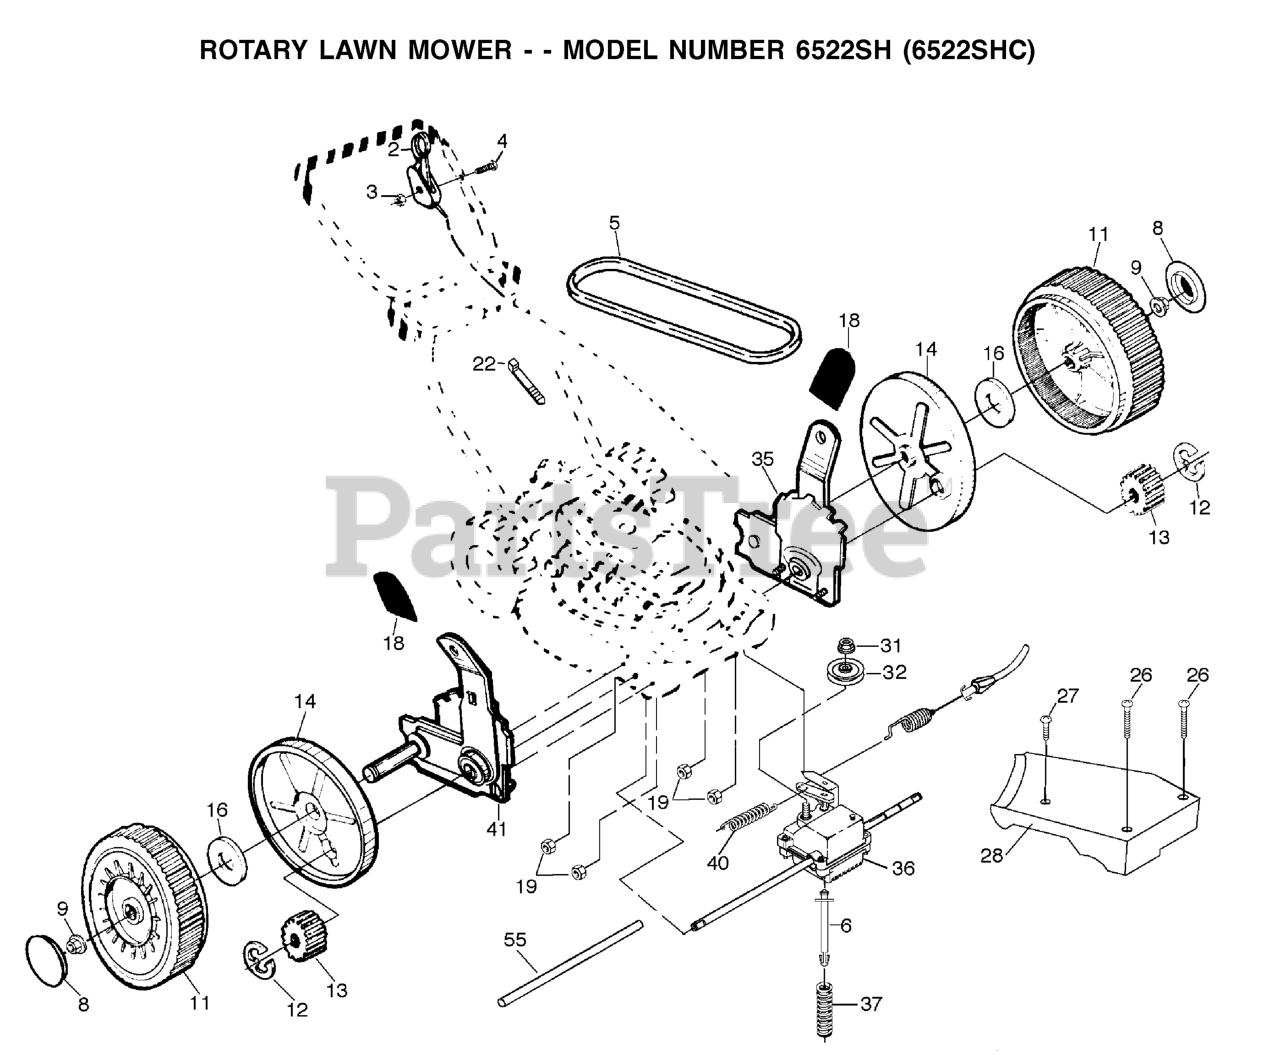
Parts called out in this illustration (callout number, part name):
2	CONTROL
3	LOCK NUT
4	SCREW.PAN.HEAD
5	BELT THERM .32
6	SPRING RETAINER
8	CAP.HUB.BLACK.WALK
9	NUT
11	WHEEL.8X2.PR.LP.RADII.GY
12	E-RING 7/16 RE
13	PINION GEAR
14	DUST COVER, WHEEL
16	WASHER FLUT
19	NUT
22	TIE GUIDE
27	TAPPING SCREW
28	COVER DRIVE
31	FLANGED LOCKNUT 3/8-16 ZINC
32	PULLEY
35	WHEEL ADJ ASM (L)
36	GEAR CASE ASMBLY
37	SPRING.EXTENSION
41	KIT.ADJUSTER.ASM.(151514).RT
55	DRV SHAFT TUBE PM
